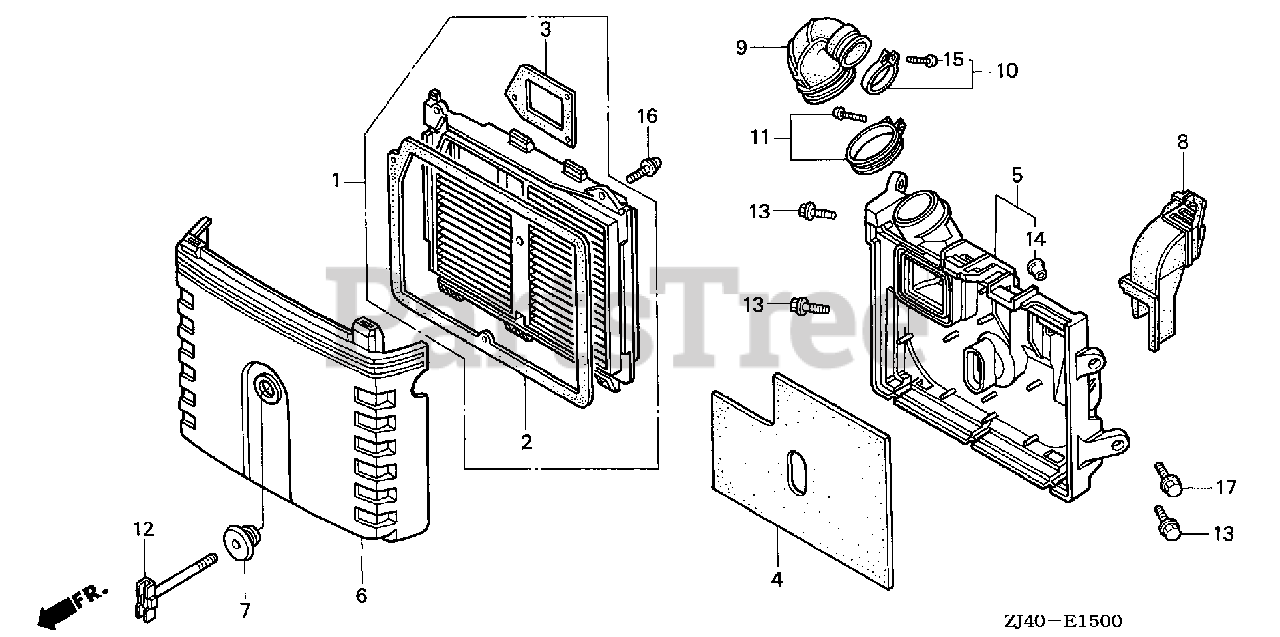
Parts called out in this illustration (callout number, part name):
1	ELEMENT SET, AIR CLEANER
2	GASKET A, ELEMENT
3	GASKET B, ELEMENT
4	FILTER (OUTER)
5	HOUSING, AIR CLEANER
6	COVER, AIR CLEANER
7	GROMMET, AIR CLEANER
8	HOSE, AIR CLEANER
9	TUBE, AIR CLEANER CONNECTING
10	BAND, AIR CLEANER CONNECTING TUBE
11	BAND B, CONNECTING TUBE
11	BAND B, AIR CLEANER
11	BAND, AIR CLEANER CONNECTING TUBE (50)
11	BAND, AIR CLEANER CONNECTING TUBE (52)
12	BOLT, AIR CLEANER
13	BOLT, FLANGE (6X23) (CT200)
14	COLLAR, AIR CLEANER HOUSING
15	SCREW, PAN (4X20)
16	SCREW-WASHER (5X16)
17	BOLT, FLANGE (6X18)
